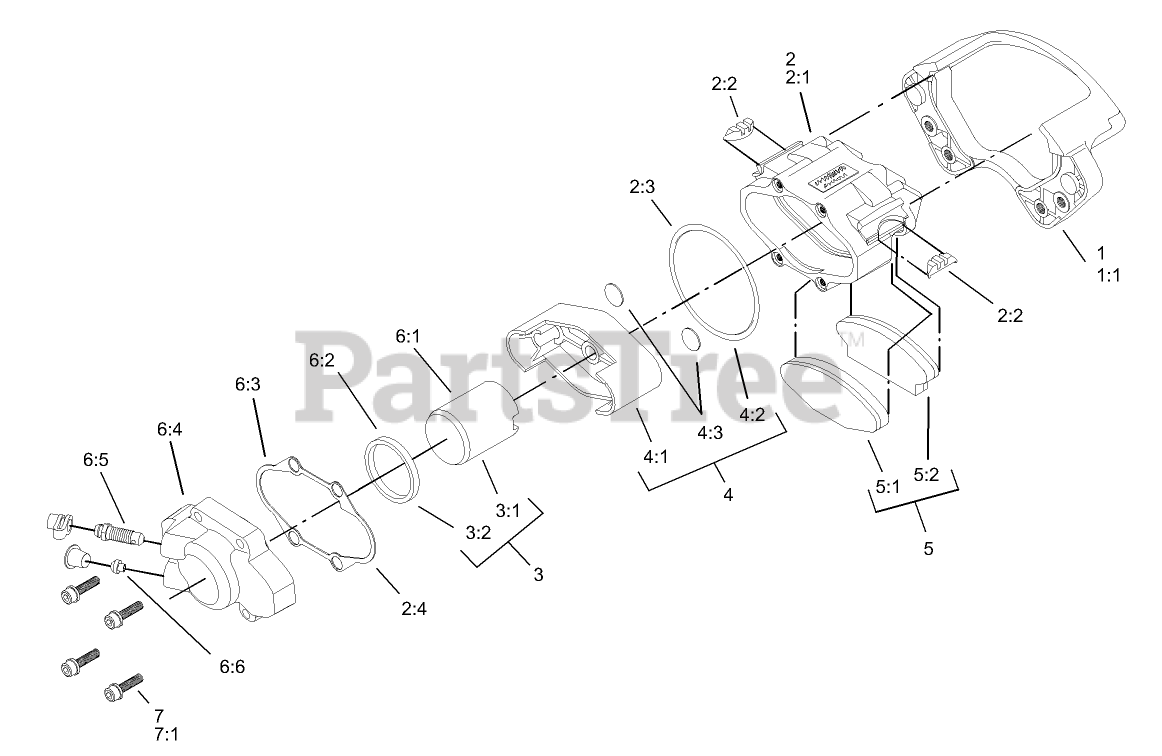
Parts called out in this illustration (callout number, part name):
1	BRACKET KIT
1:1	Bracket
2:1	Loose Parts Package
2:2	Loose Parts Package
2:3	Loose Parts Package
2:4	Gasket
3	PISTON & SEAL KIT
3:1	Loose Parts Package
3:2	Loose Parts Package
4:1	Loose Parts Package
4:2	Loose Parts Package
4:3	Loose Parts Package
5	PAD KIT
5:1	Loose Parts Package
5:2	Loose Parts Package
6	LH PISTON & COVER ASM KIT
6:1	Loose Parts Package
6:2	Loose Parts Package
6:3	Gasket
6:4	Cover
6:5	Loose Parts Package
6:6	Loose Parts Package
7	BOLT KIT
7:1	Loose Parts Package
